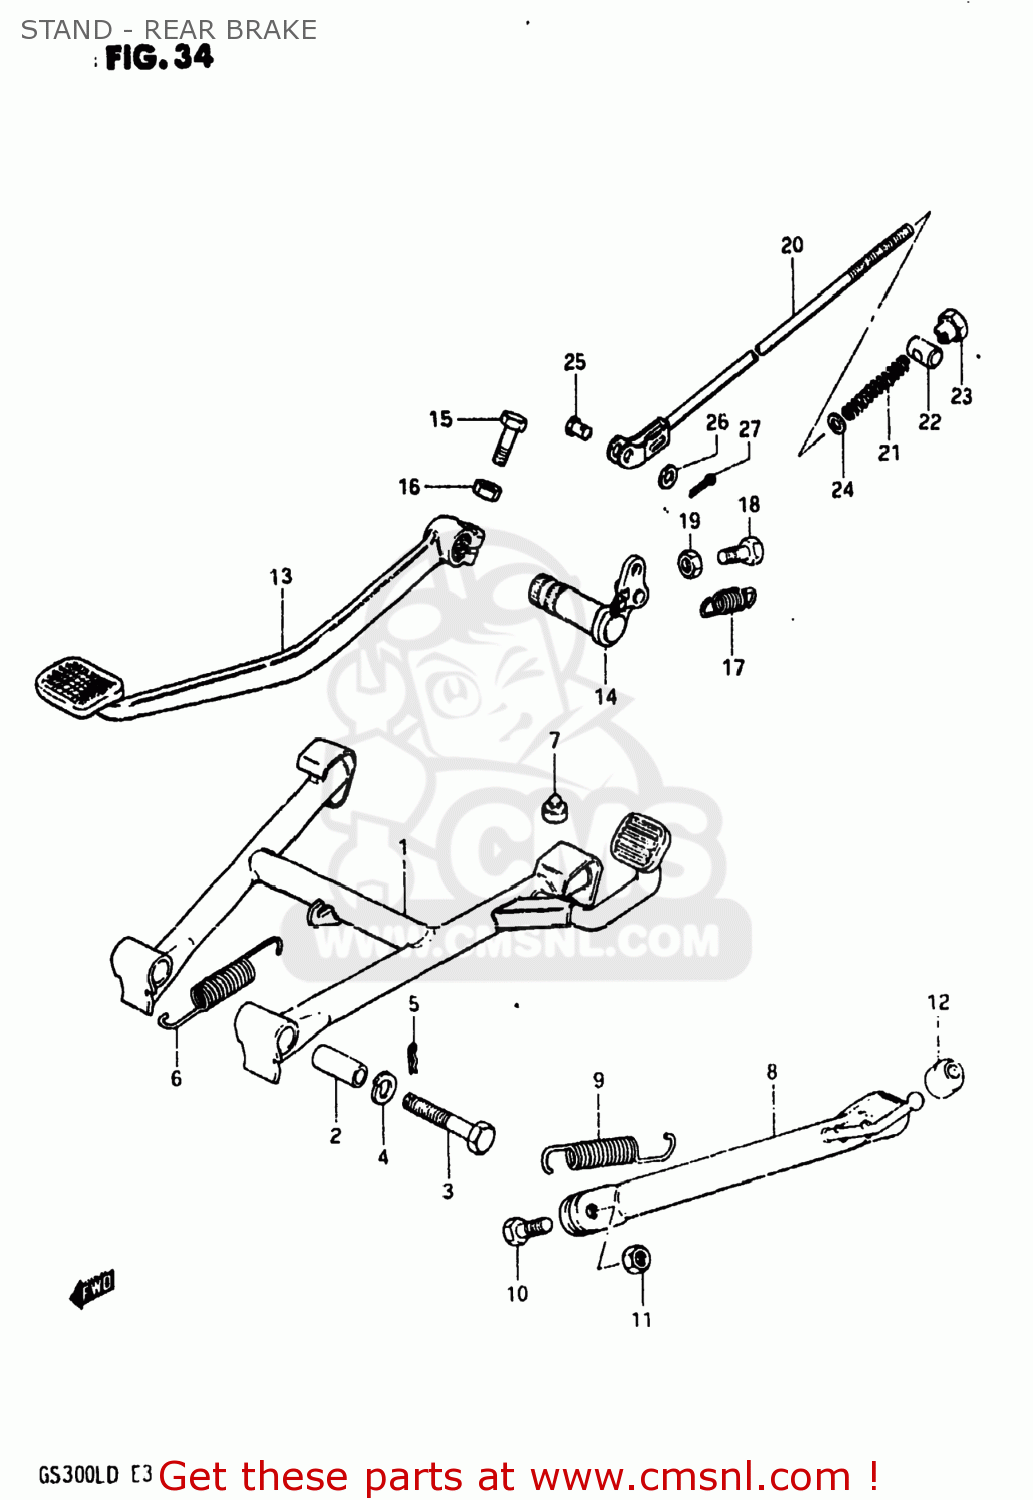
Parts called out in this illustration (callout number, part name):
1	STAND,CENTER
2	SPACER(10X16X38.8)
3	BOLT
4	LOCK WASHER
5	CLIP
6	SPRING
7	CUSHION
8	STAND,SIDE
9	SPRING
10	BOLT(10X30)
11	NUT
12	CUSHION
13	PEDAL,BRAKE
14	ARM,BRAKE PEDAL
15	BOLT
16	LOCK WASHER
17	SPRING
18	BOLT
19	NUT
20	ROD ASSY,RR BRAKE
21	SPRING
22	PIN
23	NUT
24	WASHER
25	PIN(L:13.5)
26	WASHER
27	PIN 20X20
